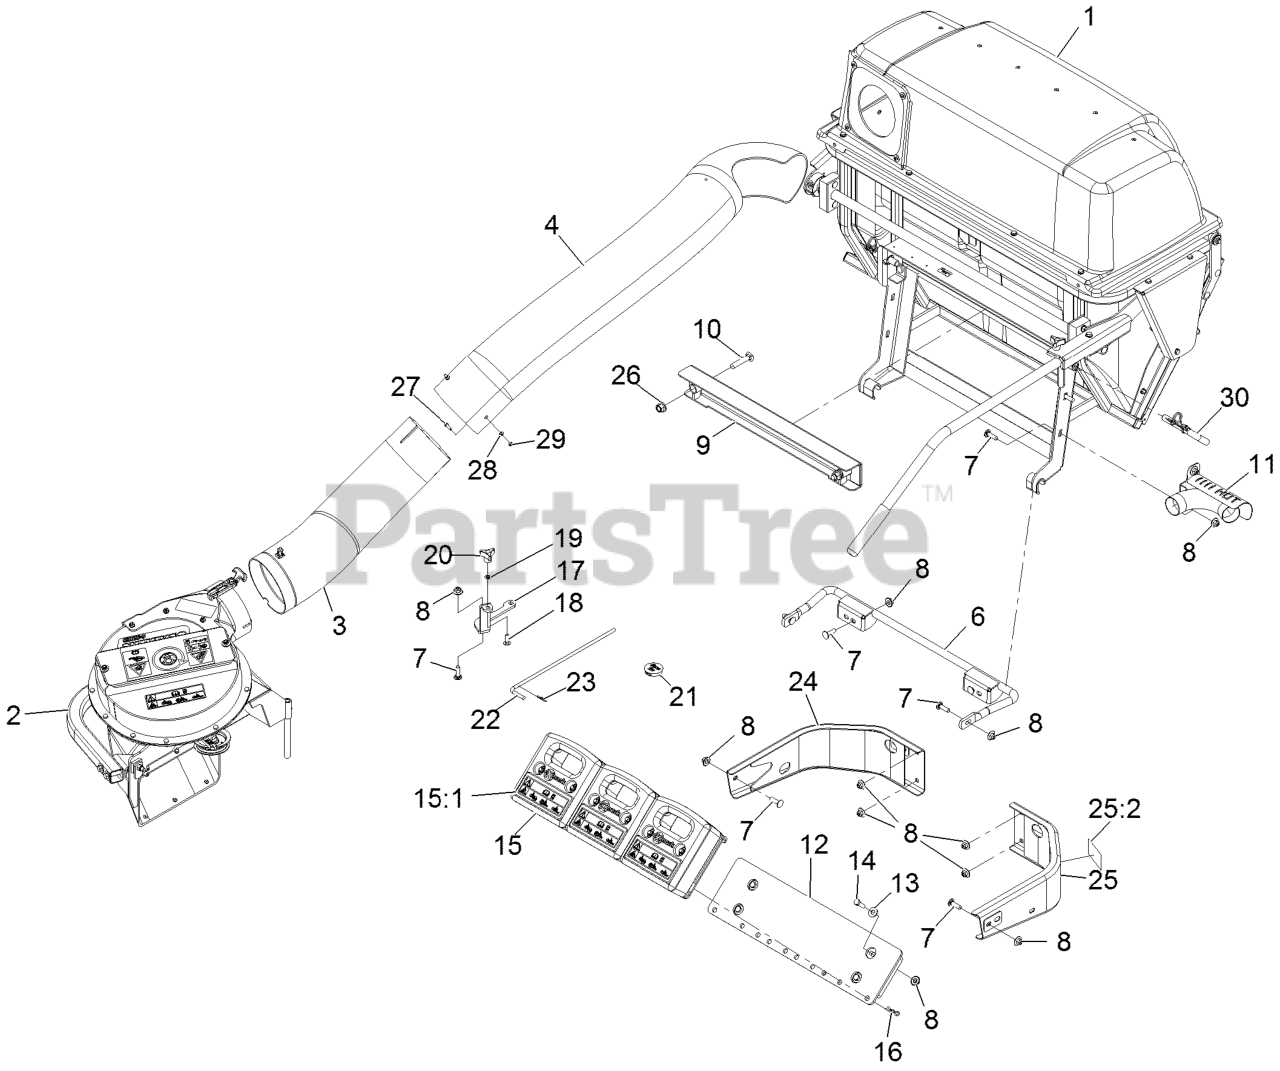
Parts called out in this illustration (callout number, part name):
1	ASM,Hopper Sm Qds
2	ASM, BLOWER SMALL - SVC O
3	LOWER TUBE ASM
4	TUBE-UPPER
6	MOUNT-BAGGER, LOWER
7	Bolt-Carriage 3/8-16 X 1 1/4
8	Nut-Nyloc 3/8-16 Flg
9	MOUNT-BAGGER, UPPER
10	SCREW-CARR
11	EXHAUST DIVERTER ASM
12	WLD, MOUNT TOEBOARD WEIGH
13	WASHER-FLAT
14	SCREW-HH
15	ASM,CAST WEIGHT
15:1	DECAL-WARNING WEIGHT
16	PIN-HAIR
17	BRACKET, SMALL UV BELT CO
18	BOLT-CARR
19	RING-RETAINING, BOLT
20	KNOB-3 PRONG
21	PLUG, BLACK NYLON 1.75
22	PIN,CHUTE PIVOT
23	PIN-COTTER
24	BUMPER-RH
25	LH BUMPER ASM
25:2	DECAL-WARNING
26	Nut-Lock 1/2-13
27	SCREW-HWH
28	WASHER-FLAT
29	NUT-LOCK, NI
30	PIN-MOUNT, BAGGER
